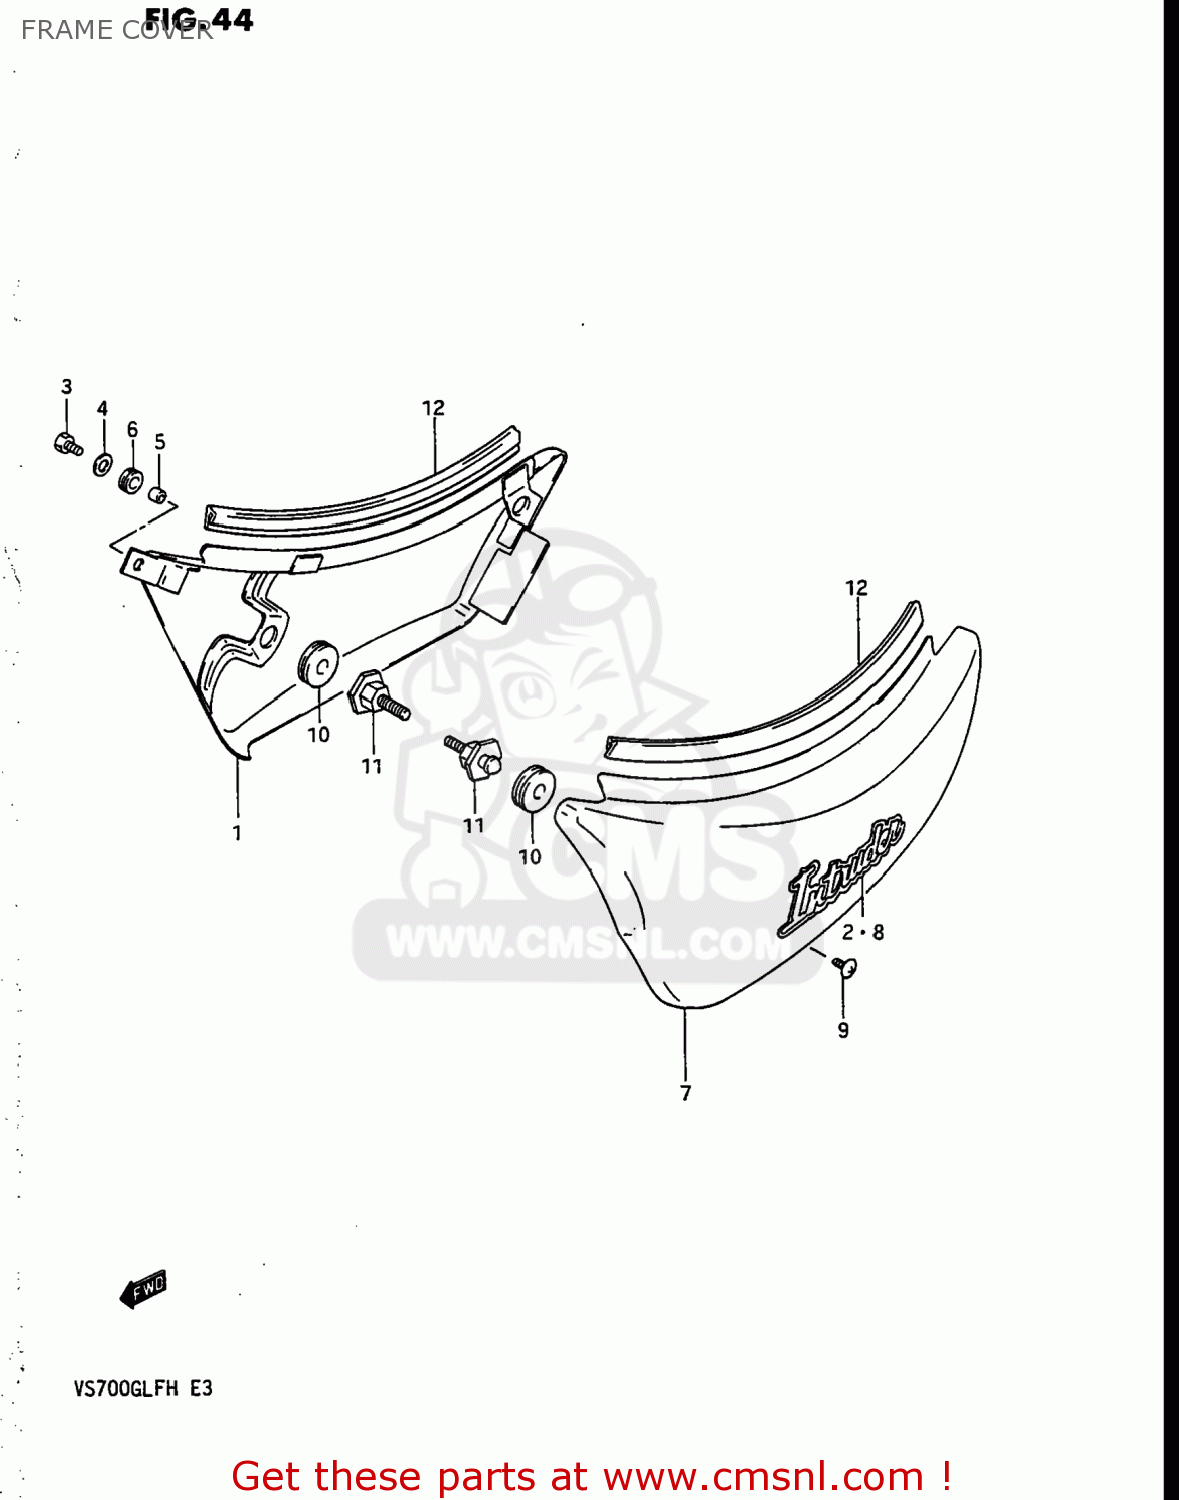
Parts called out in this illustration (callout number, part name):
1	COVER,FRAME,RIGHT
2	EMBLEM
3	BOLT
4	WASHER(6.5X18X1.6)
5	SPACER (6.1X8X5.2)
6	CUSHION
7	COVER,FRAME,LEFT
8	EMBLEM
9	SCREW
10	CUSHION
11	BOSS,FRAME COVER
12	MOLDING, FRAME COVER
